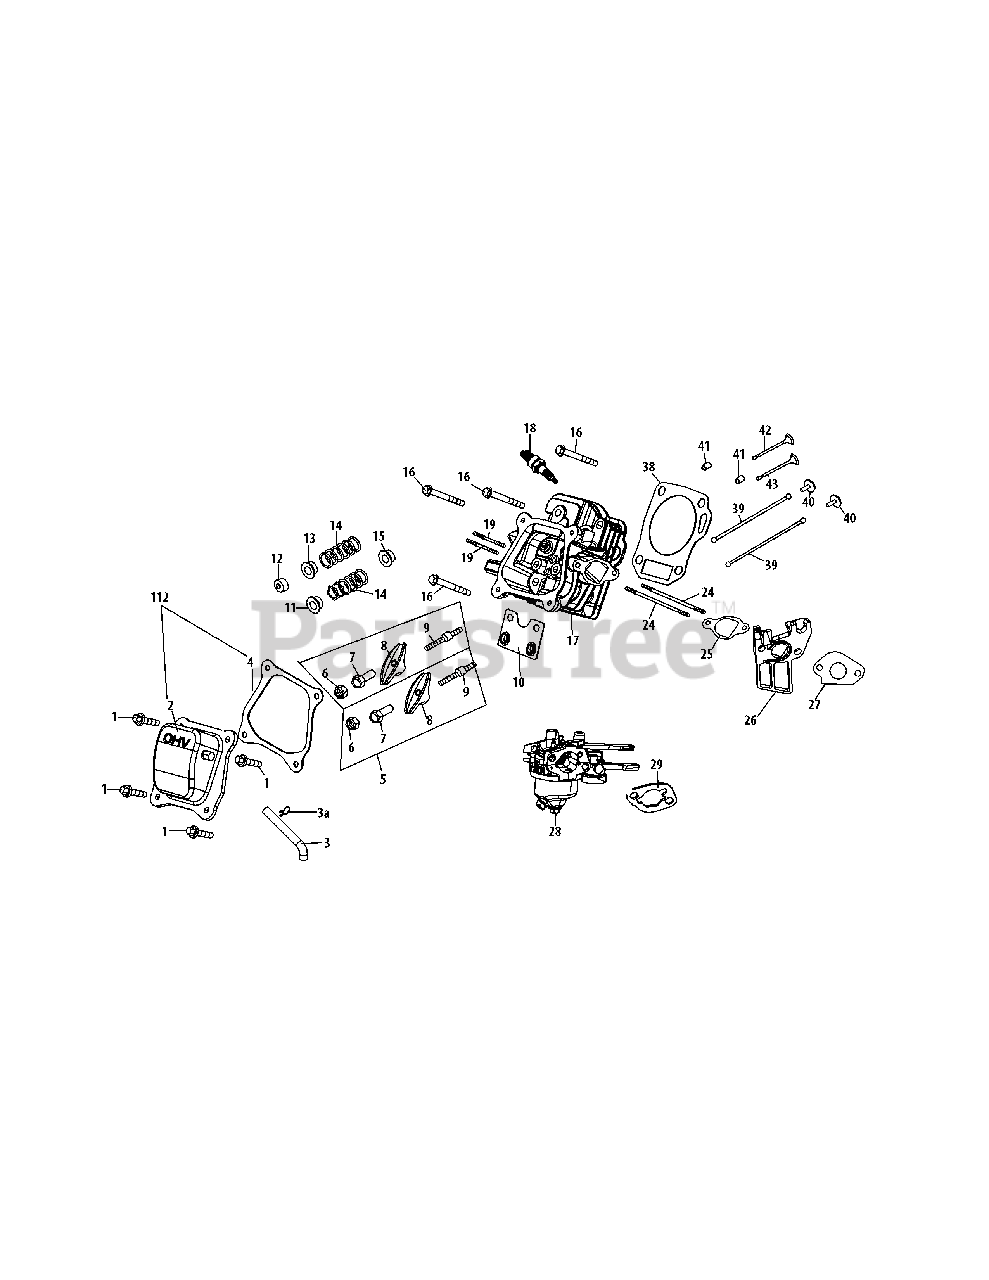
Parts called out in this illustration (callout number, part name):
1	Bolt M6×16
2	Valve Cover
4	Valve Cover Gasket
5	Roker Arm Assembly
6	Nut, Pivot Locking
7	Adjusting Nut ,Valve
8	Rocker Arm
9	Bolt, Pivot
10	Push Rod Guide
11	Retainer, In.Valve Spring
12	Adjuster, Exh Valve
13	Retainer, Ex.Valve Spring
14	Valve Spring
15	Intake Valve Seal
16	Bolt M8×55
17	Cylinder Head Assembly
18	Spark Plug
19	Muffler Stud M8×36
19	Muffler Stud Assembly
24	Stud M6×110
25	Carburetor Insulator Gasket
26	Carburetor Insulator
27	Carburetor Gasket
28	Carburetor Assembly
29	Carburetor Gasket Plate
38	Gasket, Cylinder Head
39	Push Rod Kit
41	Dowel Pin 10×16
112	Valve Cover Kit
